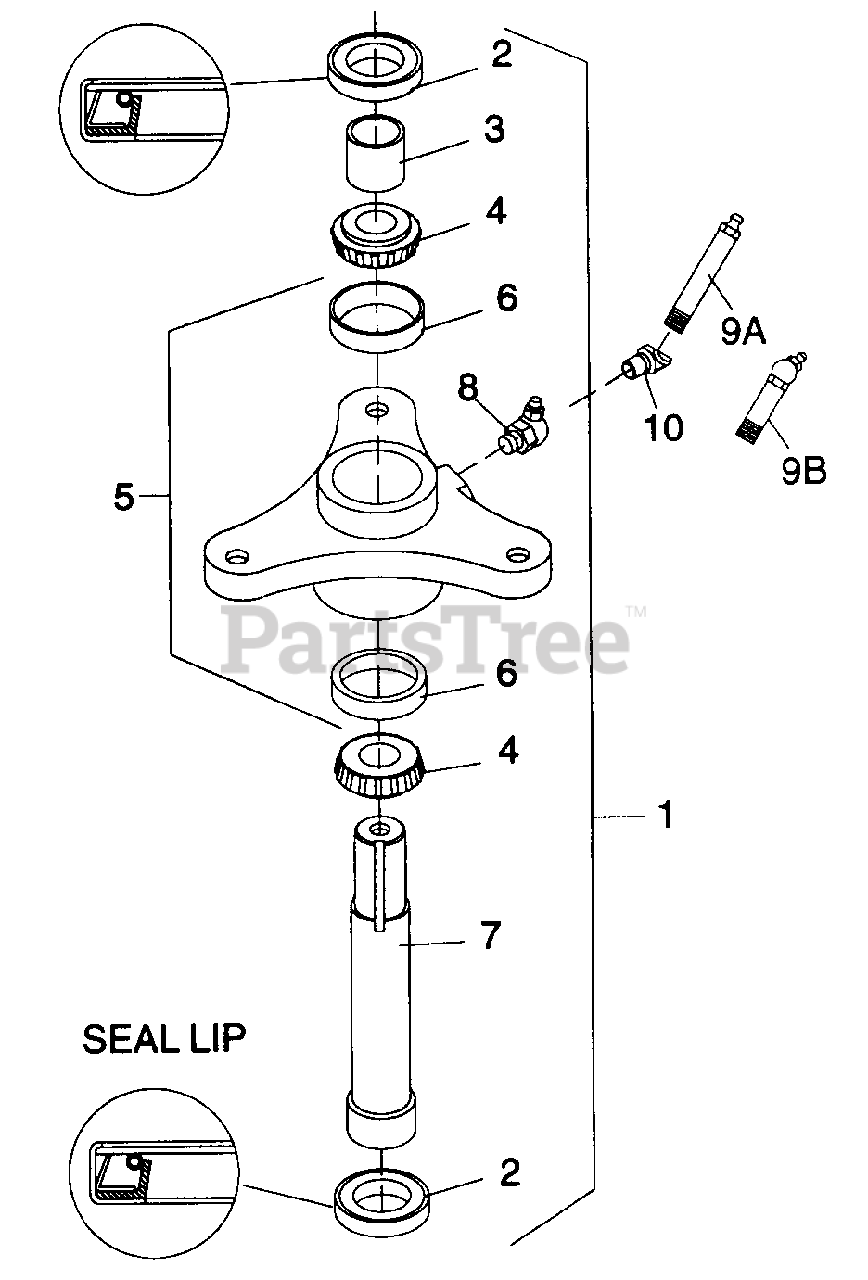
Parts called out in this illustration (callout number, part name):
1	3-Bolt CW blade spindle assembly
2	Seal, 1.063 x 2.004 x .256
3	Sleeve, .84 x 1.06 x 1.125
4	Bearing cone #M12649
5	Spindle housing with cups
6	Bearing cup #M12610
7	Spindle shaft, Right hand threads
8	1/8 Pipe thread 45ø grease fitting
9A	1/8M PTF x 2.63 Grease fitting for right and center spindles
9B	1/8M PTF x 2.09 30ø Grease fitting for left spindle
10	1/8F x 1/8M PTF 45ø Grease fitting
